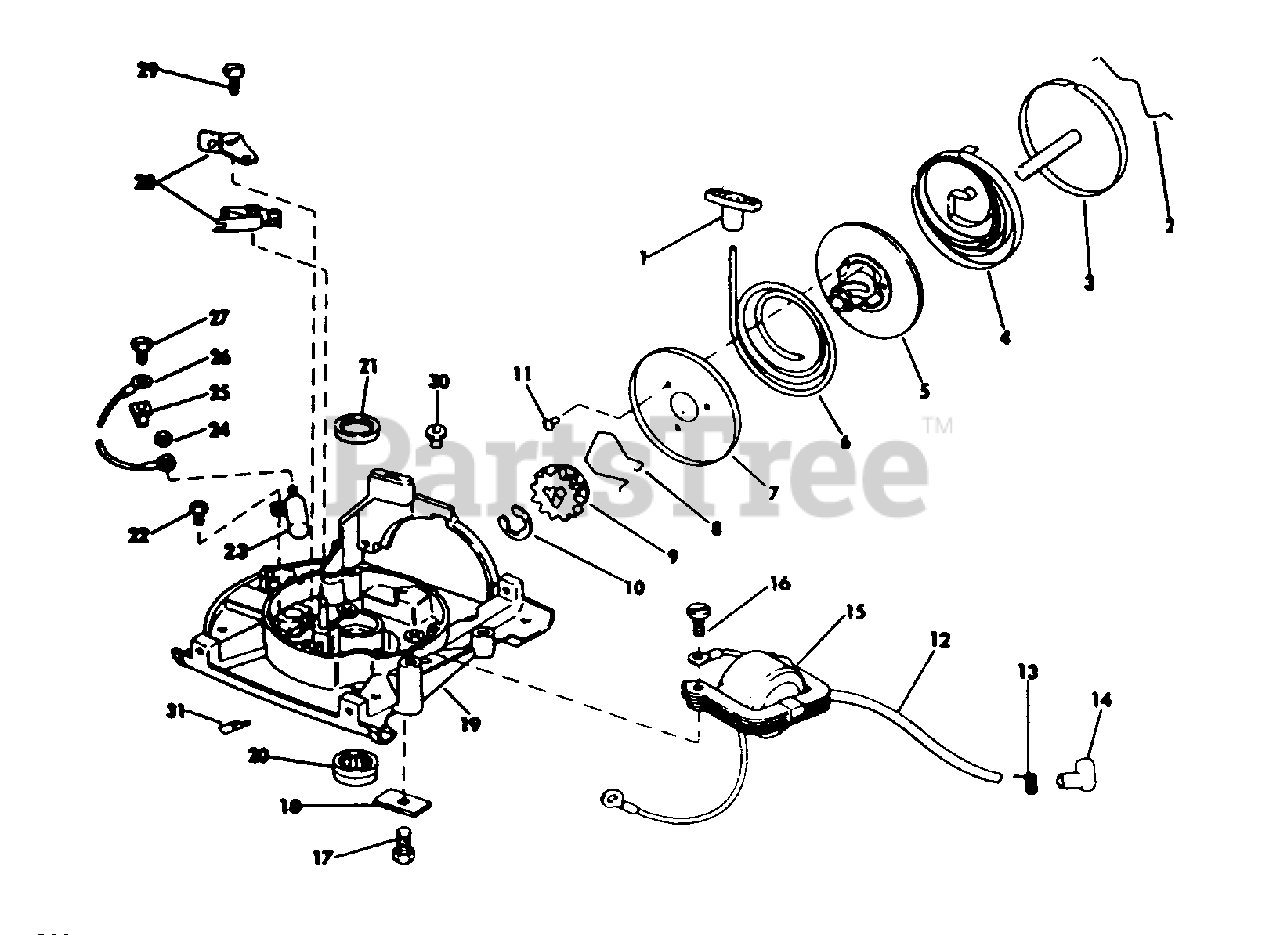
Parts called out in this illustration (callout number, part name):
1	Handle-Starter
2	Spring-Starter Rope Retainer
3	Spring-Cup-Pin Assy.
4	Spring-Starter
5	Pulley-Starter
6	Rope-Starter
7	Plate-Starter Pulley
8	Spring-Starter Pinion
9	Pinion-Starter
10	Retainer-Push-On
11	Screw-Threaded Cutting Starter
12	High Tension Lead Assy.
13	Terminal-Spring
14	Cover-Rubber
15	Coil & Lamination Assy.
16	Screw-Lamination Mtg.
17	Screw-Starter Attach.
18	Clamp-Starter Pin
19	Arm. Pl., Brg. & Oil Seal Assy.
20	Brg. & Seal Assy.
21	Oil Seal
22	Screw-Cond. Mtg.
23	Cond. & Nut Assy.
25	Grommet-Nylon
26	Terminal & Lead Assy.
27	Screw-Shut-Off Switch
28	Brkr. Base & Arm Assy.
29	Screw-Breaker Base
30	Grommet
